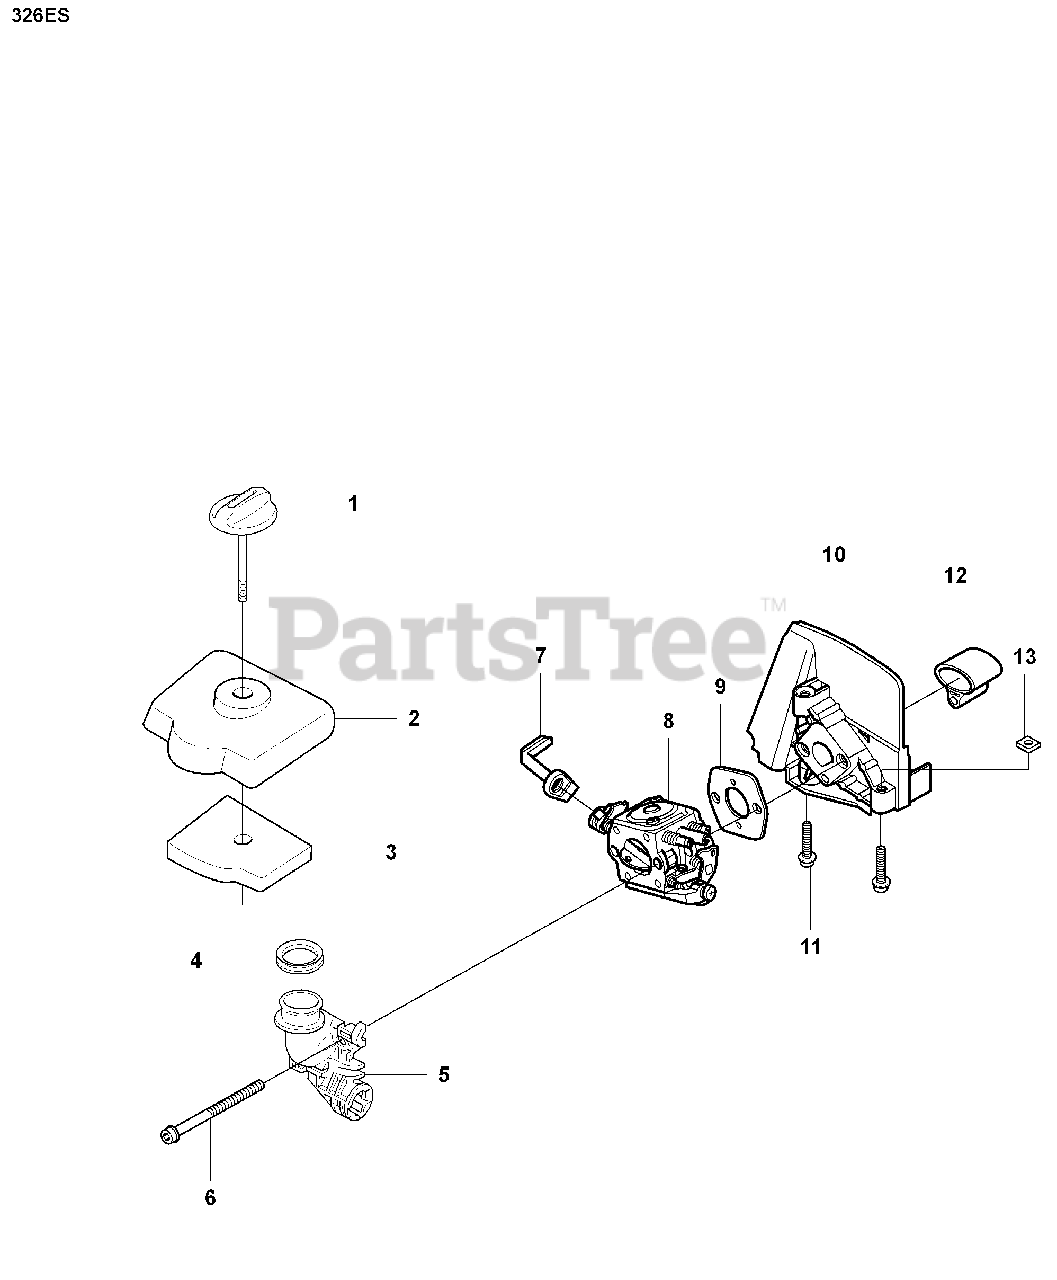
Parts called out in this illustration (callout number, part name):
2	FILTER COVER
3	AIR FILTER
7	CHOKE CONTROL
8	CARBURETOR
